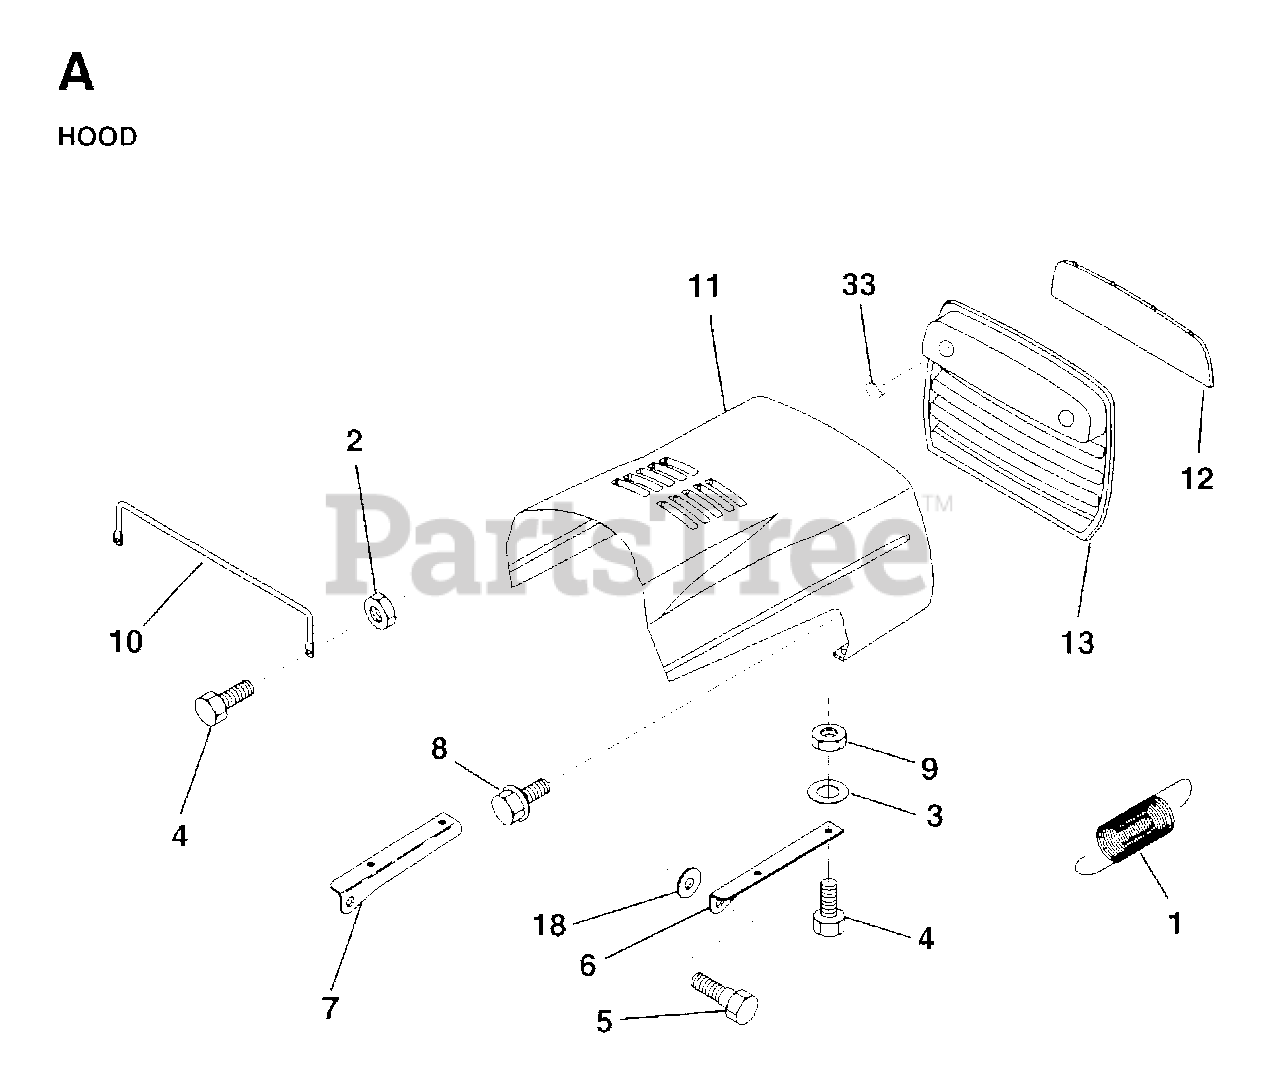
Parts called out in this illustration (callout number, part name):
1	EXT SPRING
4	BOLT
6	BRKT HOOD RH
7	BRKT HOOD LH
9	LOCKNUT
10	BRACE,HOOD
18	WASHER
20	CVR LIGHT SOCKET
